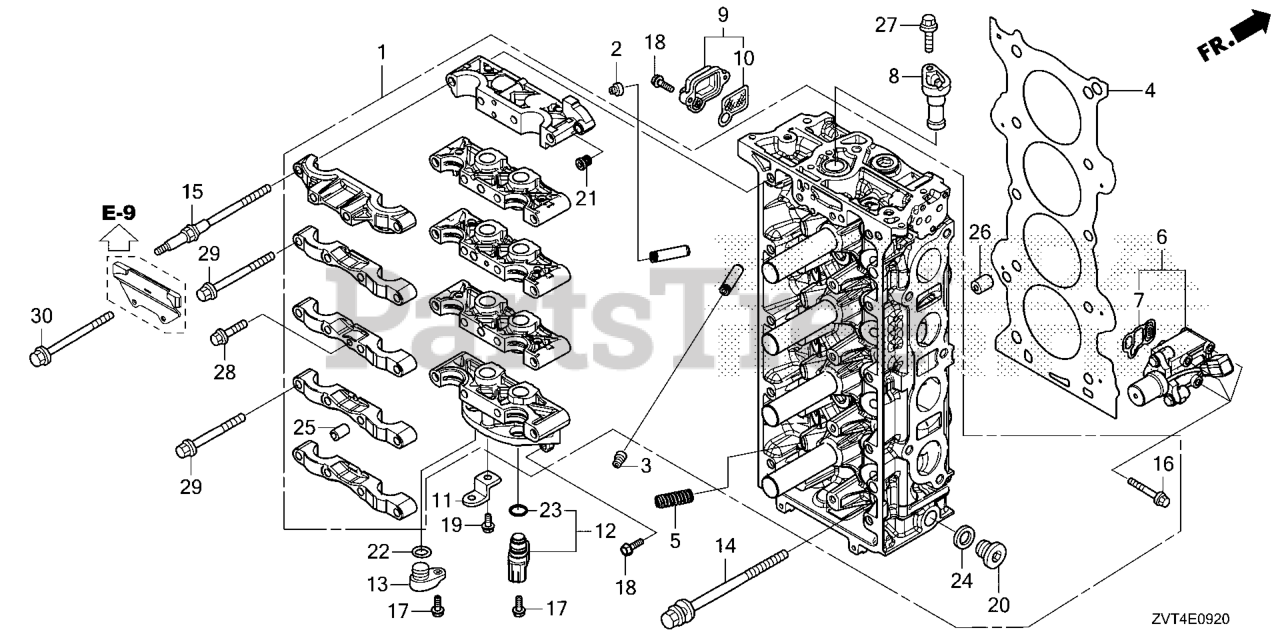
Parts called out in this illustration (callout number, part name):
1	CYLINDER HEAD KIT *NH8* (DARK GRAY)
2	SEAL A, VALVE STEM (NOK)
3	SEAL B, VALVE STEM (NOK)
4	GASKET, CYLINDER HEAD
5	MOTION, LOST
6	VALVE ASSY., SPOOL *NH8* (DARK GRAY)
7	FILTER ASSY., SPOOL VALVE
8	PLUG, VTC HOLE
9	STRAINER ASSY., VTC *NH8* (DARK GRAY)
10	FILTER ASSY., VTC
11	BRACKET F, CLIP
12	SENSOR ASSY., TDC
13	PLUG, TDC HOLE
14	BOLT-WASHER (11X155)
15	BOLT A, HEAD COVER
16	BOLT, FLANGE (6X52)
17	BOLT, FLANGE (6X16)
18	BOLT, FLANGE (6X20)
19	BOLT, FLANGE (6X14)
20	BOLT, SEALING (20MM)
21	BOLT, SEALING (10MM)
22	O-RING (15X1.9)
23	O-RING (15X1.9)
24	WASHER, DRAIN PLUG (20MM)
25	PIN A, DOWEL (10X16)
26	PIN A, DOWEL (14X20)
27	BOLT, FLANGE (6X20)
28	BOLT, FLANGE (6X32)
29	BOLT, FLANGE (8X90)
30	BOLT, FLANGE (8X110)
